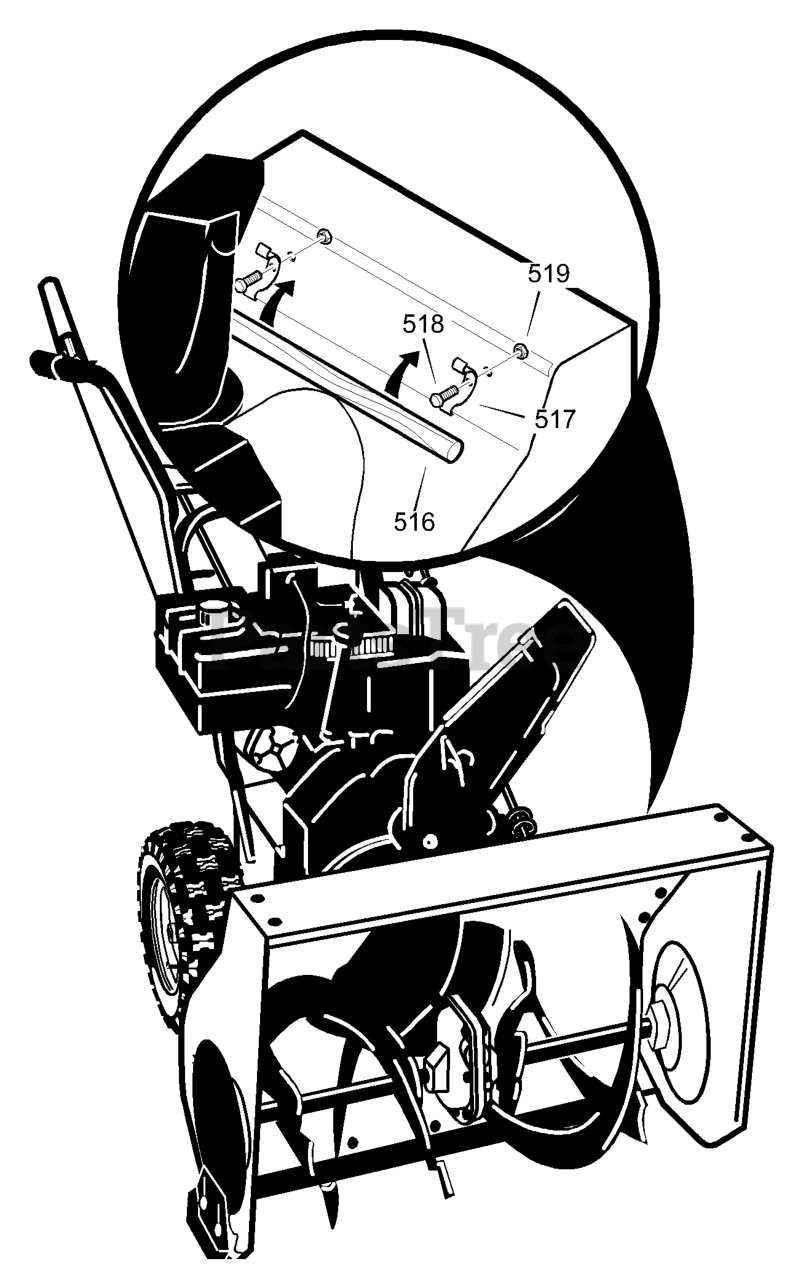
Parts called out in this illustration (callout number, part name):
516	STICK, CLEARING
517	CLIP, RETAINING
518	SCREW
